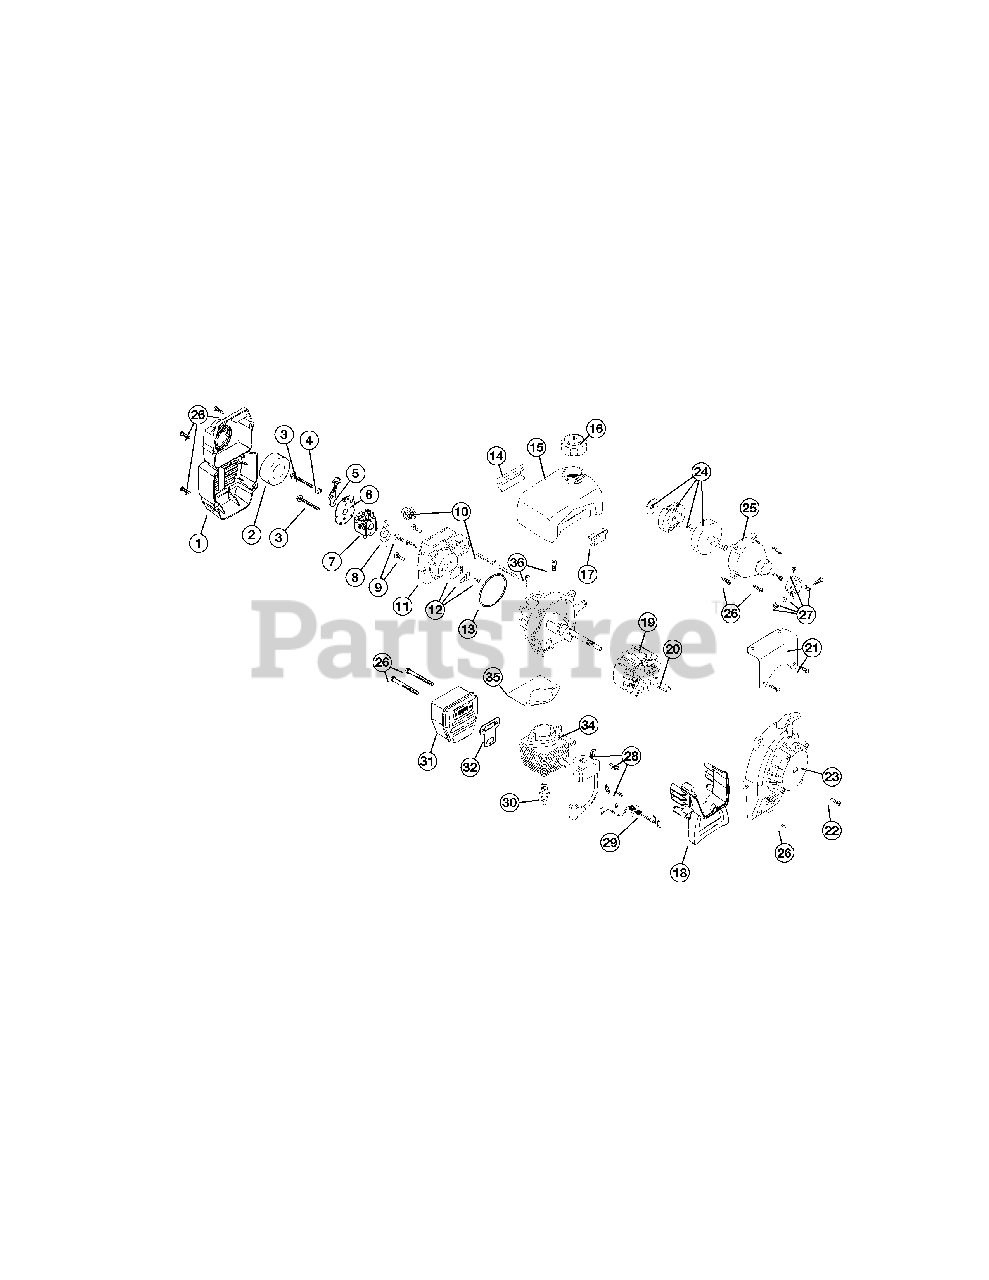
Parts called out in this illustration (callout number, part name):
1	Air Cleaner Assembly (includes 2 & 26)
2	Air Cleaner Filter
3	Carburetor Mounting Screw
4	Wavey Washer
5	Choke Lever Assembly
6	Choke Lever & Plate (includes 5)
7	Carburetor Assembly (includes 8)
8	Carburetor Gasket
9	Carb Mount Screw
10	Primer and Hose Assembly
11	Carb Mount Assembly (includes 9, 12 & 13)
12	Reed Assembly
13	Carburetor O-Ring
14	Rear Mounting Pad
15	Fuel Tank Assembly (includes 16)
16	Fuel Cap Assembly
17	Front Mounting Pad
18	Shroud Extension and Stand (includes 26)
19	Flywheel Assembly
21	Fuel Tank Guard Assembly
22	Housing Screw
23	Starter Housing Assembly (includes 22 & 26)
24	Clutch Assembly
25	Clutch Cover Assembly (includes 26)
26	Cover Screw
27	Upper Clamp Assembly
28	Module Assembly
29	Wire Lead
30	Spark Plug
31	Muffler Assembly (includes items 32, 33 & Spark Arrestor)
32	Exhaust Gasket
33	Muffler Mounting Bolt Assembly
34	Cylinder Assembly (includes 35 & 36)
35	Cylinder Gasket
36	Cylinder Bolt
